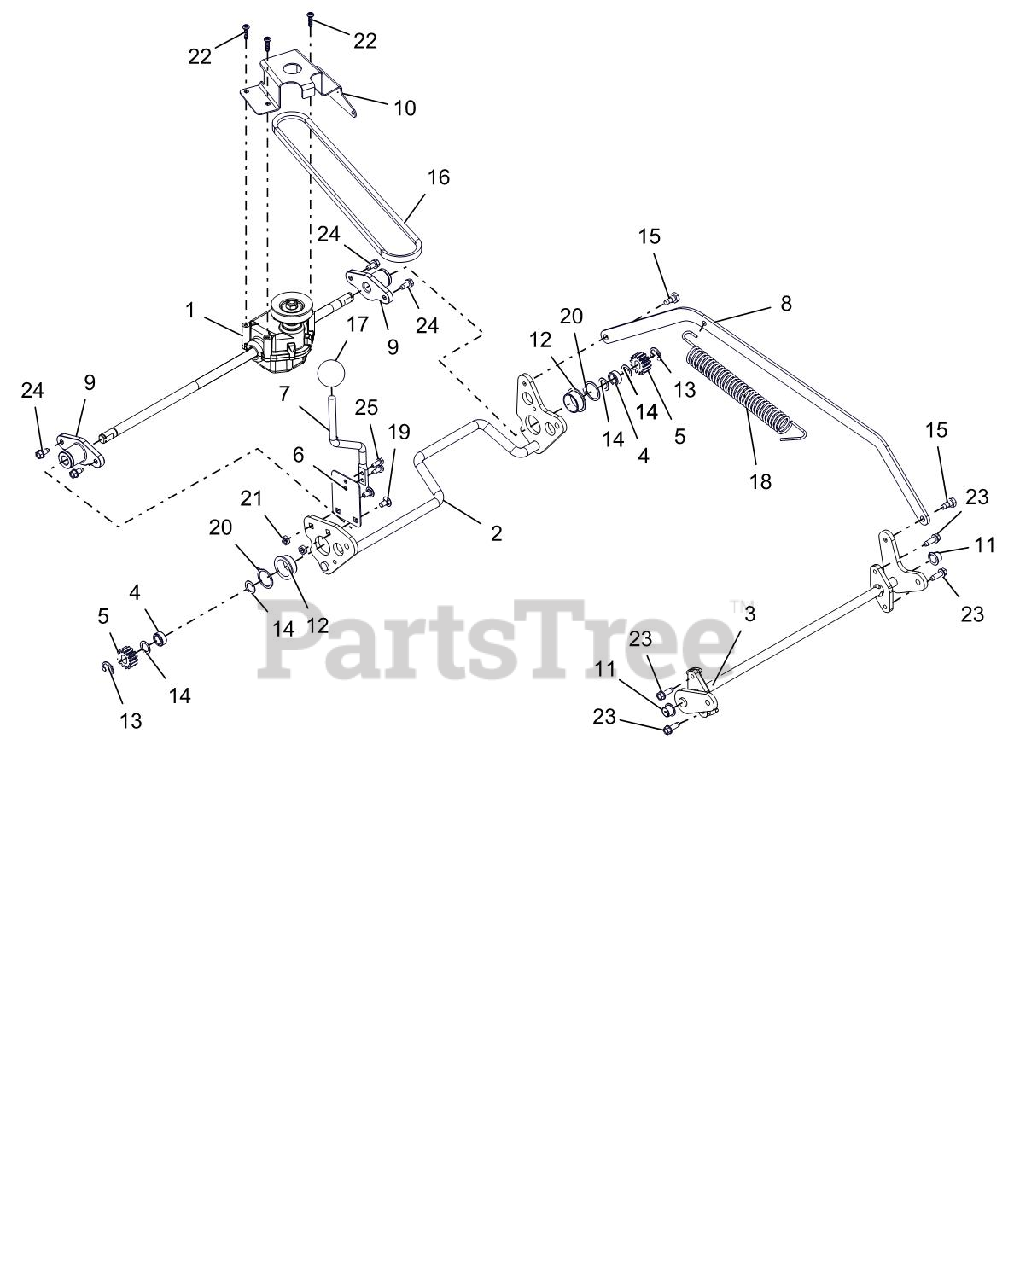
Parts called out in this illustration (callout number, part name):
1	TRANSAXLE, AUTOMATIC, LM, 9:1
2	WLDMT, REAR AXLE
3	WMT, LM FRONT AXLE
4	BSHG, SPCR.500X.750X.321 PM
5	GEAR, PINION, LM WHEEL DRIVE
6	PLATE, HOC SPRING
7	LEVER, HOC ADJUSTMENT
8	LINKAGE, HOC CONNECT
9	HUB, LM REAR AXLE
10	BRKT, TRANSMISSION BELT GUIDE
11	BUSHING, POLYLINER-.50 SPLIT
12	BSHG-FLG 1.0X1.125X.50X1.375 R
13	RG-RTNG-EXT .500X.042 (E)
14	WASHER, .500X.750X.020 THRUST
15	BOLT, SHLDR .320X.210X.25-20
16	V-BELT, 3L-WRAPPED
17	KNOB,BALL -BLACK 1.47" .375-16
18	SG-TENS .121X1.00X6.5 WLD
19	@BLT-RDHDSQNK .25-20X.50 G5YZ
20	RG-RTNG-EXT 1.00X.042
21	NUT-LK-CTR JAM .25-20 YWZC
22	SCR-TAP 10-14X.75PLSTITE BLKOX
23	SCR-TAP-PM .25-20X.75 TR YWZ
24	SCR-TAP .25-20X.50 HWH TR YWZ
25	@SCR-TAP 12-24X.50 HWH TR YWZC
